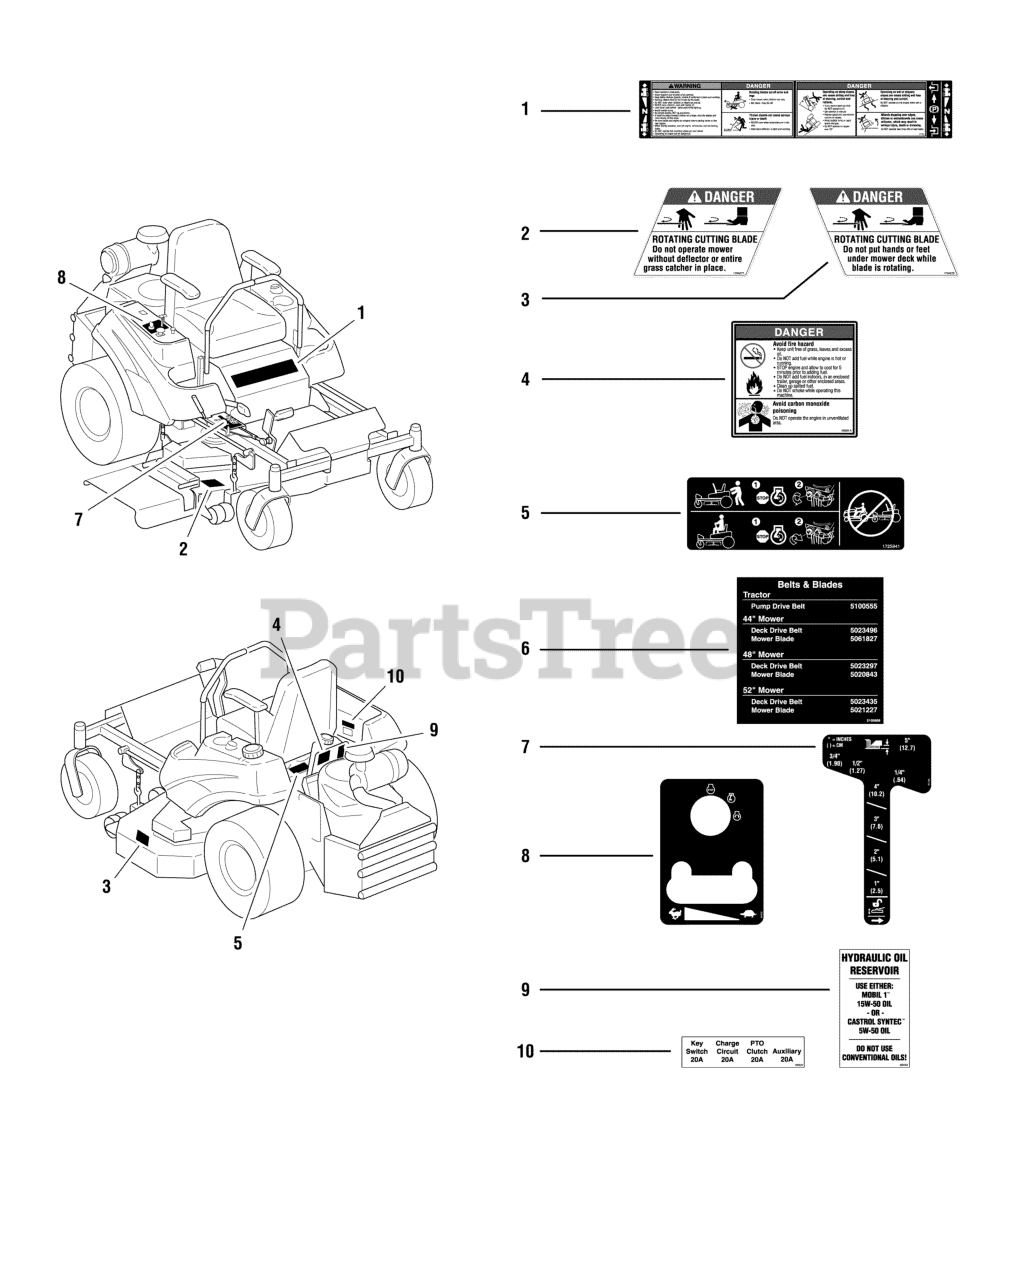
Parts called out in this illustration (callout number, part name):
1	DECAL, Main
2	DECAL, Danger (Chute In Place)
3	DECAL, Danger (Hand Under Deck)
4	DECAL, Danger
5	DECAL, CZT Hydro Release
6	DECAL, Belt & Blade
7	DECAL, Height of Cut
8	DECAL, Ignition / Throttle
9	DECAL, Oil Reservoir
10	DECAL, Fuse Location
